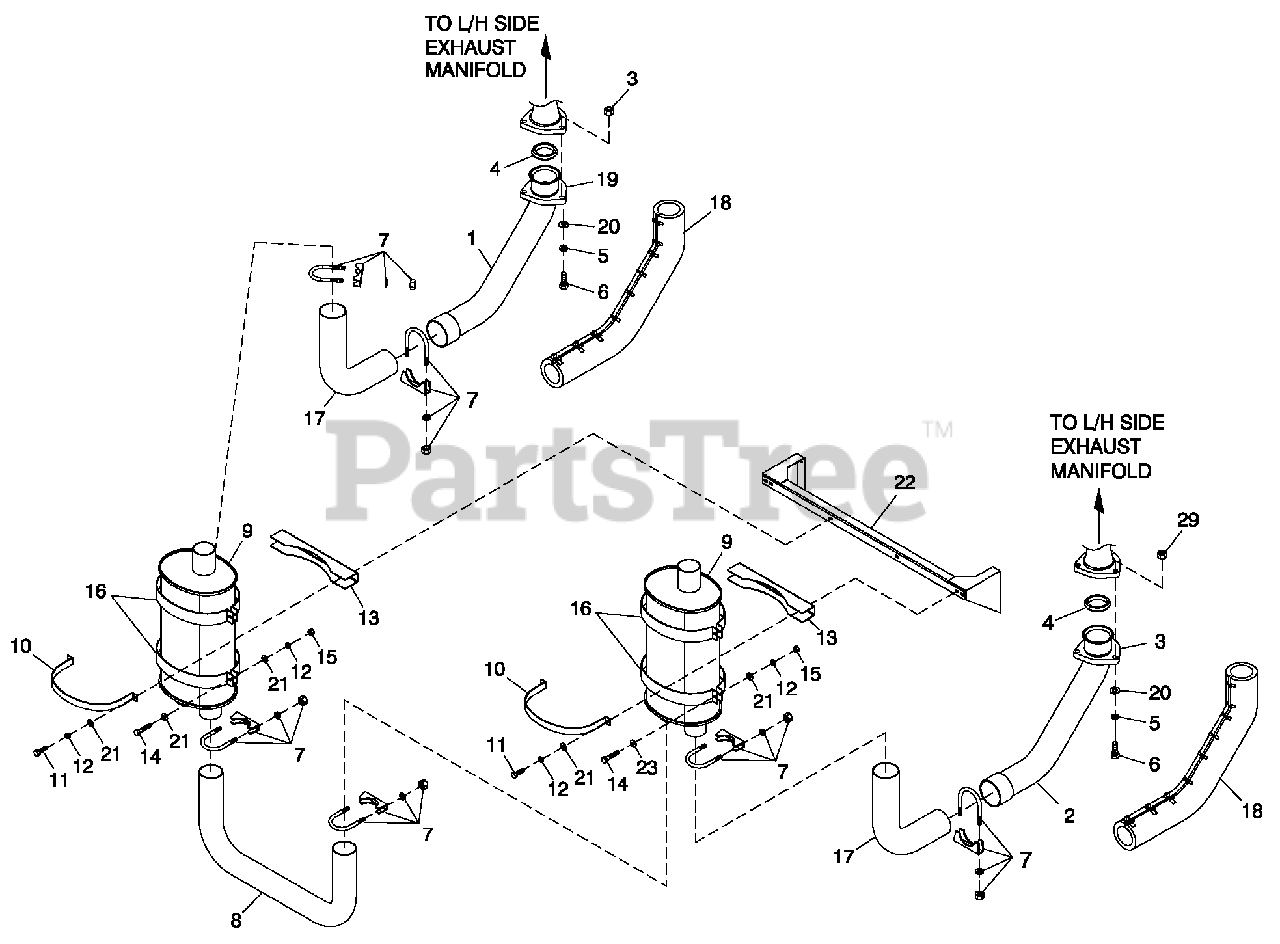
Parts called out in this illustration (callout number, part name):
1	PIPE EXH MAN R/H 6.8L G/B CPL (6.8L C5)
2	PIPE EXH MAN L/H 6.8L G/B CPL (6.8L C5)
3	NUT HEX M10-1.5 SS
4	RING GASKET 2.5 DIA
5	WASHER LOCK M10 SS
6	SCREW HHC M10-1.5 X 50 SS FTH
7	BOLT U 3/8-16 X 2.62
8	PIPE EXHAUST CROSSOVER
9	MUFFLER 7" X 9" X 25" (2) 2.5" IN/2.5" OUT
10	MUFFLER STRAP
11	SCREW HHC M6-1.0 X 16 G8.8
12	WASHER LOCK M6-1/4
13	MUFFLER BRACKET STIFFENER
14	SCREW HHC M6-1.0 X 35 G8.8 BLK
15	NUT HEX M6 X 1.0 G8 YEL CHR
16	MUFFLER STRAP UPPER/LOWER
17	PIPE ELBOW EXHAUST MUFFLER
18	EXHAUST BLANKET 900MM LONG (6.8L C5)
19	FLANGE EXHAUST
20	WASHER FLAT 3/8 SS
21	WASHER FLAT 1/4-M6 ZINC
22	BRACKET MUFFLER
